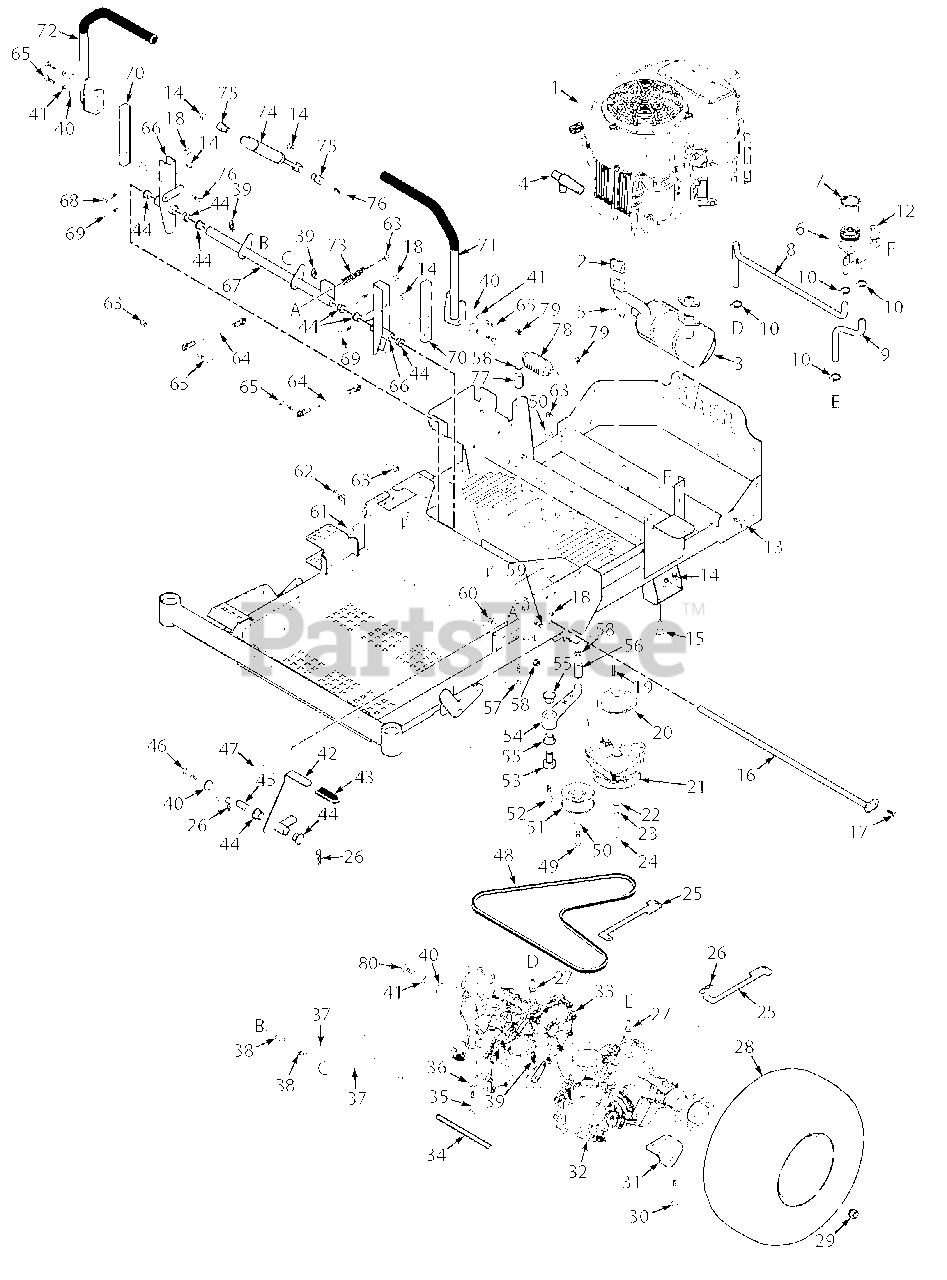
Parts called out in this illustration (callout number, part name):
1	Engine, Kawasaki - FR600V
1	Engine, Kawasaki - FR651V
2	Gasket, Exhaust
3	Muffler, Kawasaki FR/FS600V
3	Muffler, Kawasaki FR/FS651V
4	Oil Drain, Kawasaki
5	Nut, M6-1.0 Hex Flange
6	Reservoir Assembly
8	Hose, RH Transmission
9	Hose, LH Transmission
10	Clamp, .87 Max. Dia.
11	Clamp, .69 Max. Dia.
12	Nut, 1/4-20 Flange Elastic Stop
13	Bolt, Carriage 1/4-20 x 3/4"
14	Nut, 5/16-18 Elastic Stop
15	Bolt, 3/8-16 x 1-1/4" Serrated Flange Self Tap
16	Shaft Weldment, Control Arm
17	Bolt, Hex Head 1/4-20 x 5/8"
18	Nut, 1/4-20 Elastic Stop
19	Key, 1/4 x 1/4 x 1-1/4"
20	Pulley, 4-1/2" - 1" Bore
21	Clutch, GT1
22	Flatwasher, 7/16-.496 x 1.75 x .25
23	Lockwasher, 7/16"
24	Bolt, 7/16-20 x 3" w/Patch
25	Lever, Dump Valve
26	Hair Pin Cotter, .080 x 1.19
27	Fitting, O-Ring x 3/8" Hose
28	Wheel Assembly
28	Rim w/Valve Stem
28	Tire, 20 x 10-8
29	Wheel Nut, 1/2-20 x 13/16
30	Bolt, Hex Head 5/16-18 x 3"
31	Bracket, Pusharm
32	Transaxle, LH - SZL
33	Transaxle, RH - SZL
34	Spacer
35	Bolt, Hex Head 5/16-18 x 2-1/4"
36	Flatwasher, 5/16-.375 x .875 x .083
37	Rod, Brake
38	Joint, Swivel
39	Pin, Rue Cotter - 3/8"
40	Flatwasher, 3/8-.391 x .938 x .105
41	Lockwasher, 3/8"
42	Brake Lever Assembly
43	Grip, Brake Handle
44	Bearing
45	Pivot, Brake Lever
46	Bolt, Hex Head 3/8-16 x 2-1/2"
47	Rod, Upper Brake Linkage
48	Belt, Transmission-SZL
49	Bolt, Hex Head 3/8-16 x 3-3/4"
50	Flatwasher, 3/8-.391 x .938 x .105 HD
51	Pulley, 3-1/2" Idler
52	Bolt, Hex Head 3/8-16 x 3"
53	Shaft, Pivot Idler Arm
54	Idler Arm Assembly
55	Bearing
56	Spacer, Pump Idler
57	Bolt, Hex Head 3/816 x 2"
58	Nut, 3/8-16 Serrated Flange
59	Bolt, Hex Head 1/4-20 x 1"
60	Nut, 1/4-20 Serrated Flange
61	Bolt, Hex Head 3/8-16 x 2-1/2" Special Lock
62	U-Nut, 3/8-16
63	Nut, 3/8-16 Elastic Stop
64	Linkage, Pump
65	Bolt, Hex Head 3/8-16 x 1-1/4"
66	Control Arm Assembly
67	Bellcrank Assembly
68	Bolt, Hex Head 1/4-20 x 1-3/4"
69	Bolt, Hex Head 5/16-18 x 1-3/4"
70	Bar, Control Lever
71	Handlebar w/Grip
71	Grip, Control Lever
72	Handlebar w/Grip
72	Grip, Control Lever
73	Spring, Brake
74	Damper, Steering
75	Spacer, Damper
76	Bolt, Hex Head 5/16-18
77	Spacer
78	Spring, Transmission Drive
79	Nut, 3/8-16 Center Lock
80	Bolt, Hex Head 1/4-20 x 1-1/2
